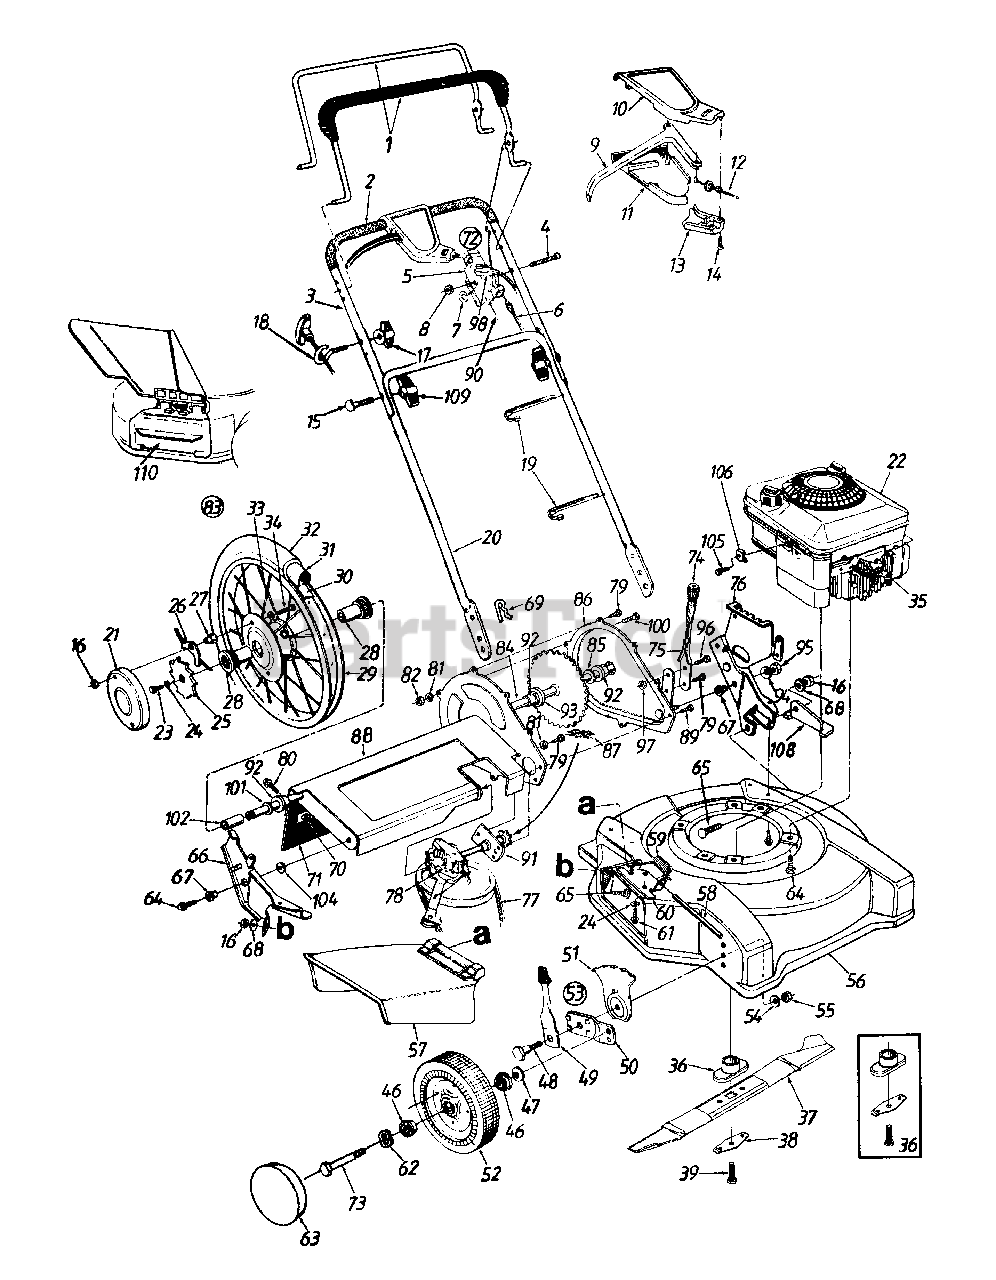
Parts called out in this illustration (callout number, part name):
1	Control Handle Ass'y.
2	Foam Grip
4	Oval C-Sunk Scr.
5	Throttle Body
6	Control Cable-39" Lg.
7	Spring Wash. .66" I.D.
8	Hex L-Nut 1/4-20 Thd.
9	Control Lever
10	Control Cover Half-Upper
11	Control Cover Half-Lower
12	Self-Propelled Cable-48" Lg.
13	Cable Mounting Cap
14	Fl-"C" Sunk Hd. Tap Scr.#10 x .75" Lg.
15	Curved Hd. Bolt 5/16-18 x 2" Lg.
16	Hex Nut 5/16-18 Thd.
17	Handle Knob 1/4-20 Thd.
18	Rope Guide
19	Cable Tie
22	Engine
23	Hex Bolt 1/4-20 x .75" Lg. (Gr. 5)
24	Bell-Wash. 1/4" I.D.
25	Wheel Ratchet
26	Pawl and Spring Ass'y.
27	Special Hex Nut 5/16-18 Thd.
28	Flange Bearing .63" I.D.
29	Rim Ass'y. Only 16" x 2.1"
30	Rimstrip 16" x 7/8"
31	Inner Tube 16" x 2.12"
32	Chevron Tire 16" x 2.125"
33	Intern. L-Wash. 5/16" I.D.
34	Hex Bolt 5/16-18 x 1.0" (Gr. 5)
35	Spark Plug Boot
36	Blade Adapter Kit
37	.21" Mulching Blade
38	Blade Bell Support
39	Hex Bolt 3/8-24 x 1.5" Lg.
46	Ball Bearing 1/2" I.D.
47	Bell-Wash. .38" I.D.
48	Shld. Bolt.5"
49	Spring Lever Ass'y. w/Knob
51	Height Adj. Plate
52	Wheel Ass'y. Comp.
54	Bell-Wash. .39" I.D. x 1.38"
55	Hex Nut 3/8-16 Thd.
58	Hinge Pin
59	Torsion Spring
60	Adapter Plate
61	Hex TT-Tap Scr. 1/4-20 x .5"
62	Wave Wash. .51" I.D. x .78"
63	Hub Cap
64	Hex TT-Tap Scr. 3/8-16 x 1"
65	Carriage Bolt 5/16-18 x .62" Lg.
68	Bell-Wash. 5/16" I.D.
69	Intern. Cotter Pin 5/16" Dia.
70	Retaining Strip
71	Rear Flap
72	Throttle Box Comp.
73	Front Axle Bolt
75	Height Adjustment Lever
78	Transmission Comp.(See Breakdown)
79	Hex Tap Scr. 1/4 x .38" Lg.
80	Hex Tap Scr. 1/4 x .62" Lg.
81	L-Wash. 1/4" I.D.
82	Hex Nut 1/4-20 Thd.
83	Wheel Ass'y. Comp.
84	Sprocket and Axle Ass'y.
85	Fl-Wash. .635" I.D. x 1.0" O.D.
90	Throttle Cable
92	Hex Flange Brg. .631" I.D.
93	Spacer .63" I.D. x 1.25"
94	Fl-Wash. .385" I.D. x .87" O.D.
95	Hex L-Nut 3/8-24 Thd.
96	Hex Bolt 3/8-16 x .62" Lg.
97	Flanged L-Nut 3/8-16 Thd.
98	Throttle Lever
100	Hex Bolt 1/4-20 x .5" Lg.
101	Fl-Wash. .632" I.D. x .943"
102	Spacer .628" I.D. x .875"
104	Fl-Wash. .38" I.D. x 1" O.D.
105	Wash. Hd. Scr. #10-32 x .62" Lg.
106	Casing Clamp
108	Deck Bracket
109	Hand Knob
110	Mulching Baffle
